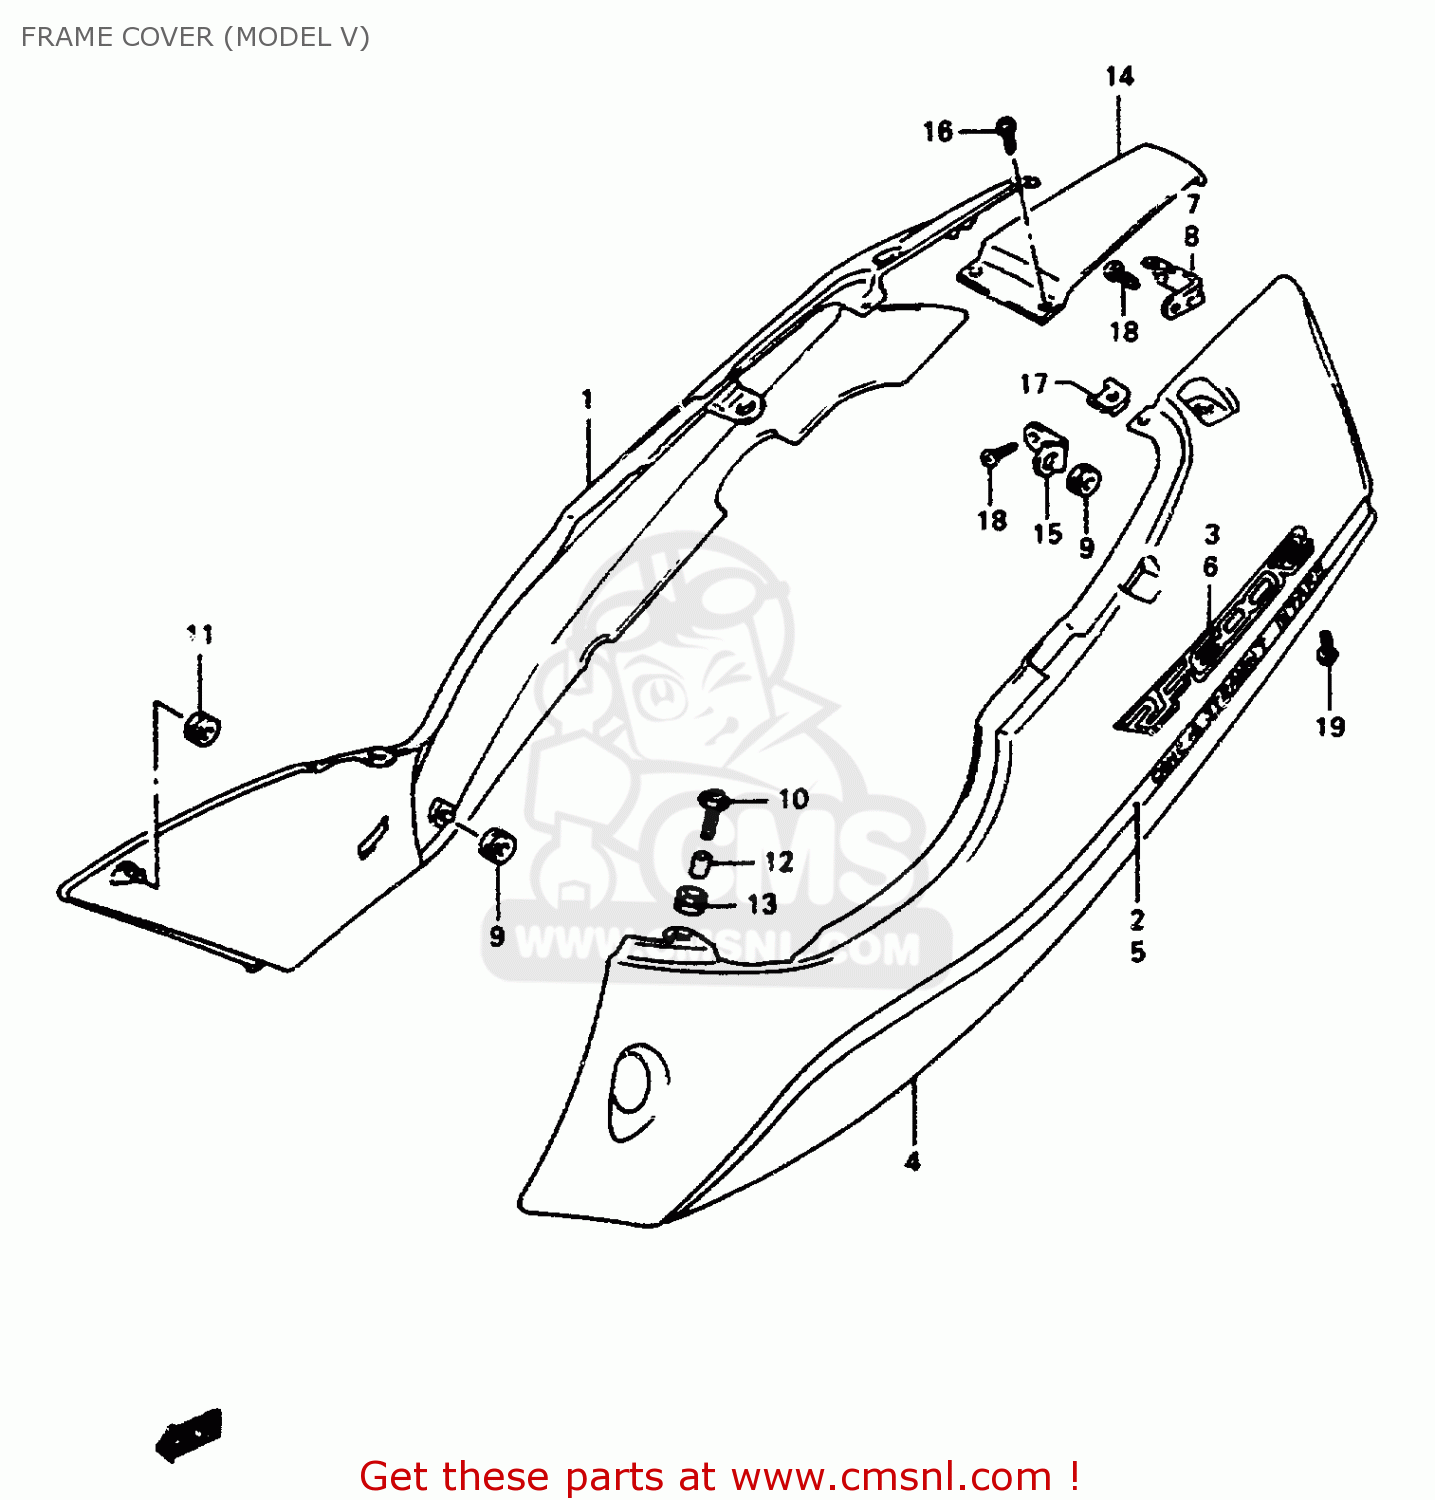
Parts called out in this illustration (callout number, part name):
1	2
2	TAPE SET,FRAME COVER STRIPE,R
3	EMBLEM,FRAME COVER
4	COVER ASSEMBLY,FRAME,LEFT
5	TAPE SET,FRAME COVER S
6	EMBLEM,FRAME COVER
7	BRACKET,FRAME COVER,R
8	CUSHION
9	SCREW
10	BOLT(6X25)
11	SPACER
12	CUSHION
13	COVER,FRAME CTR
14	COVER,FRAME CTR
15	SCREW
16	NUT
17	SCREW
18	SCREW
19	SCREW 5X12
